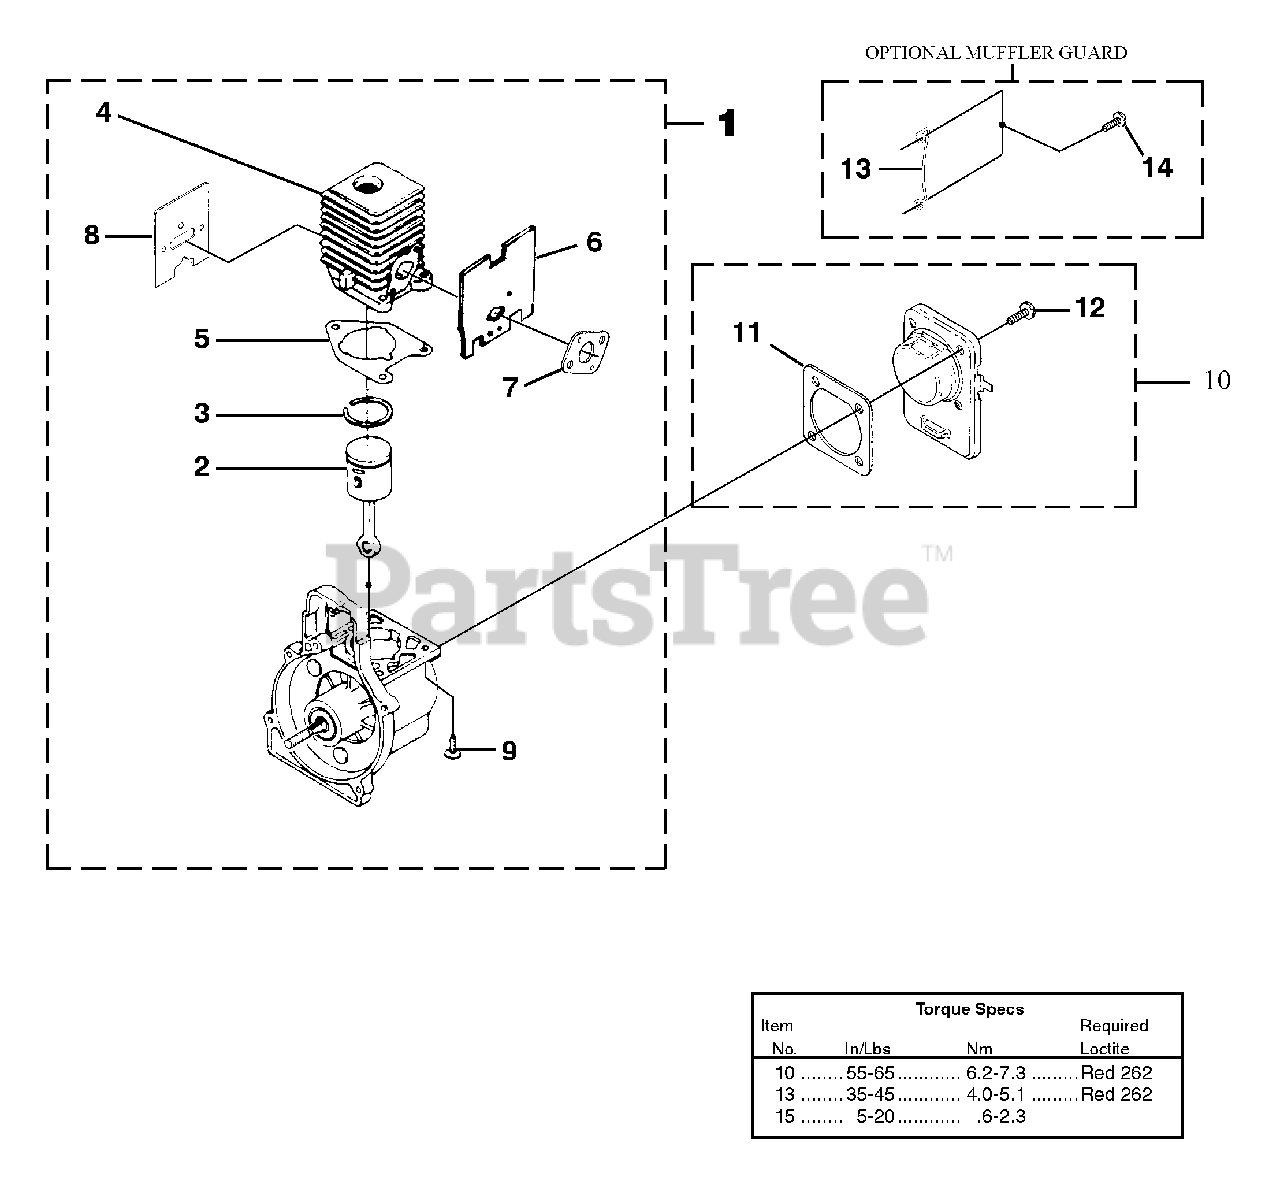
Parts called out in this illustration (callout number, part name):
1	SHORT BLOCK
2	PISTON & ROD ASSY.
3	RING-Piston
4	CYLINDER ASSY.
5	GASKET-Cylinder
6	GASKET-Heat Dam
7	GASKET-Carburetor
8	GASKET-Muffler
9	SCREW-Sems (12-24 X 3/4")
10	CRANKCASE COVER ASSEMBLY
11	GASKET-Crankcase Cover
12	SCREW-Sems (10-24 X 1/2")
13	MUFFLER GUARD
14	SCREW-Thread Forming (10-14 X 1/2")
